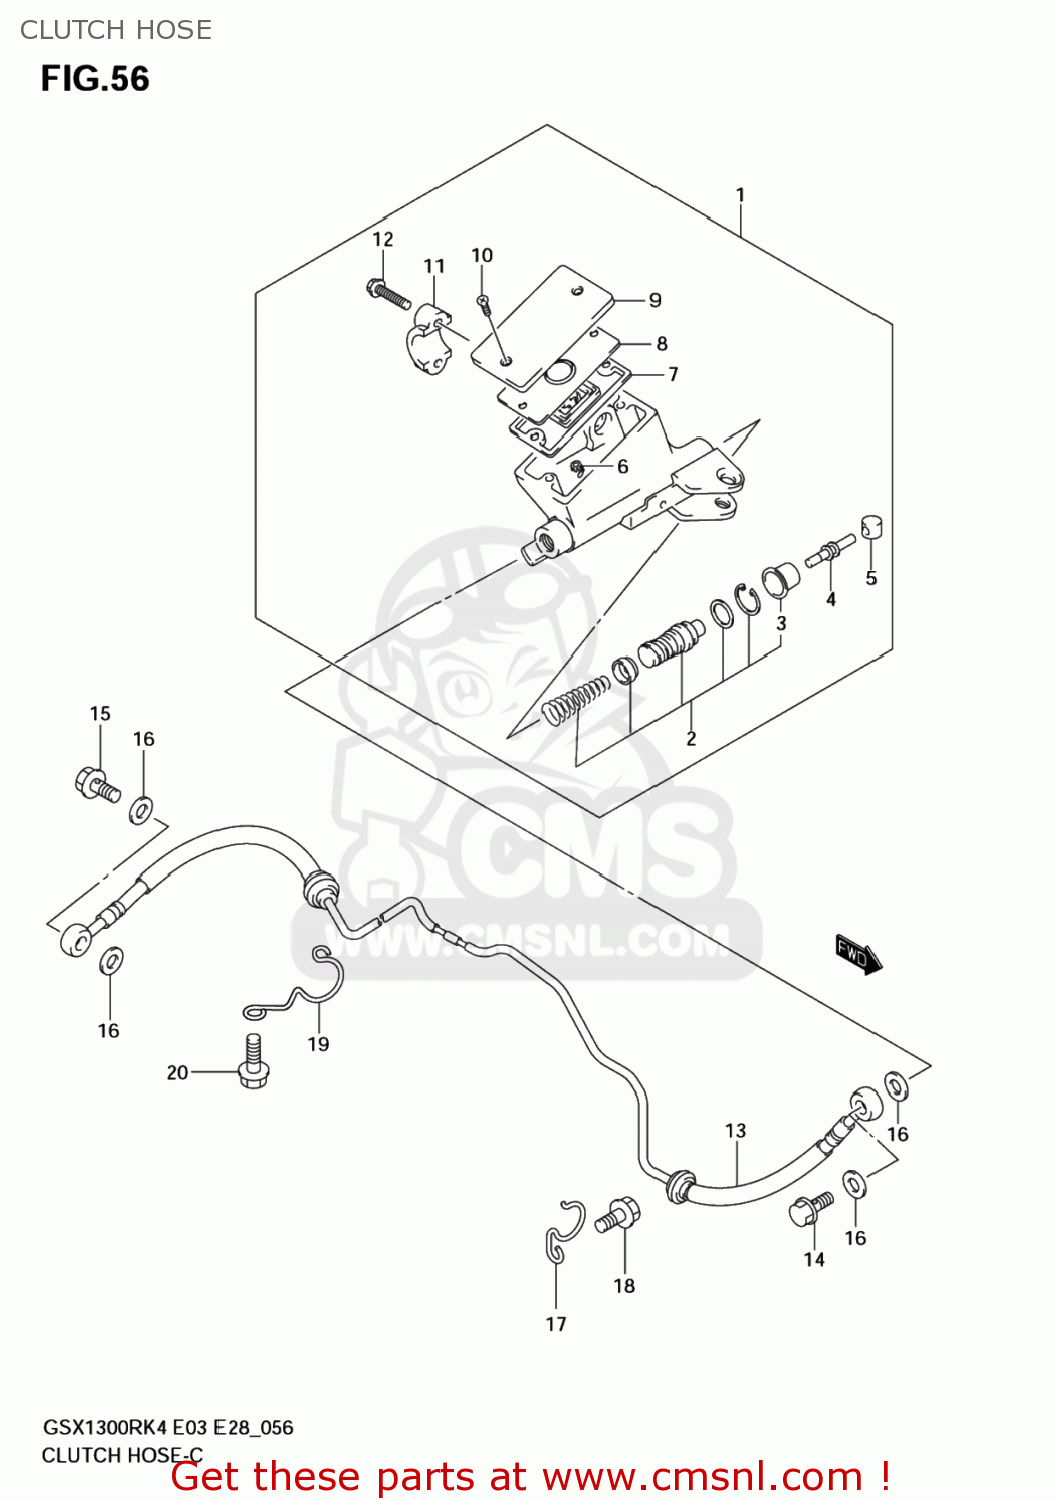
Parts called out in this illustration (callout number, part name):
1	CYLINDER ASSEMBLY,CLUTCH MASTER
2	PISTON & CUP SET
3	BOOT
4	PUSH ROD
5	BUSH
6	PROTECTOR
7	8
8	PLATE,DIAPHRAGM
9	CAP
10	SCREW
11	HOLDER
12	BOLT(6X22)
13	HOSE,CLUTCH
14	BOLT UNION
15	BOLT UNION
16	WASHER(10X15X1.5)
17	CLAMP,CLUTCH HOSE NO.1
18	BOLT
19	CLAMP,CLUTCH HOSE NO.2
20	BOLT
